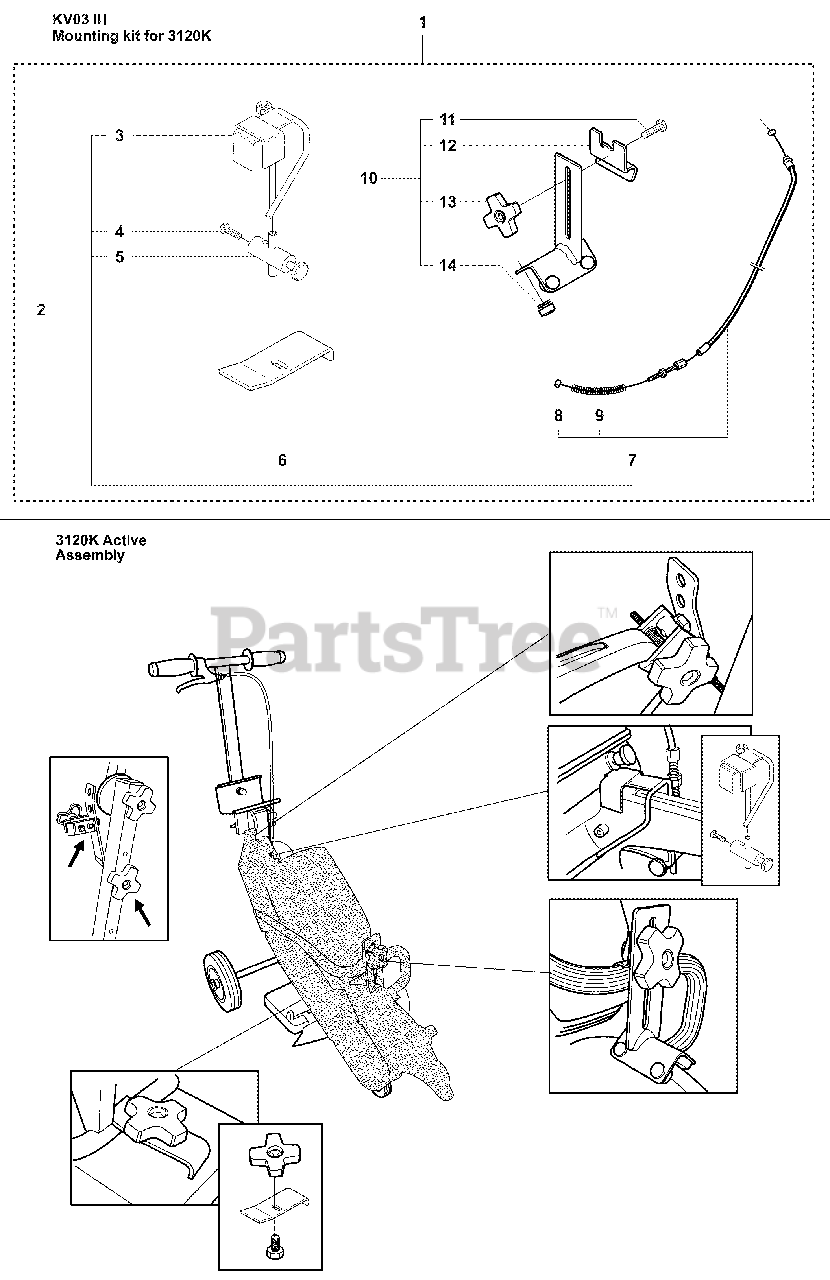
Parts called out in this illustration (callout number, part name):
1	ASSEMBLY KIT
2	KIT
6	PRESSURE PLATE
7	THROTTLE WIRE
8	CABLE RETAINER
9	COMPRESSION SPRING
10	RETAINER
13	STEERING WHEEL
